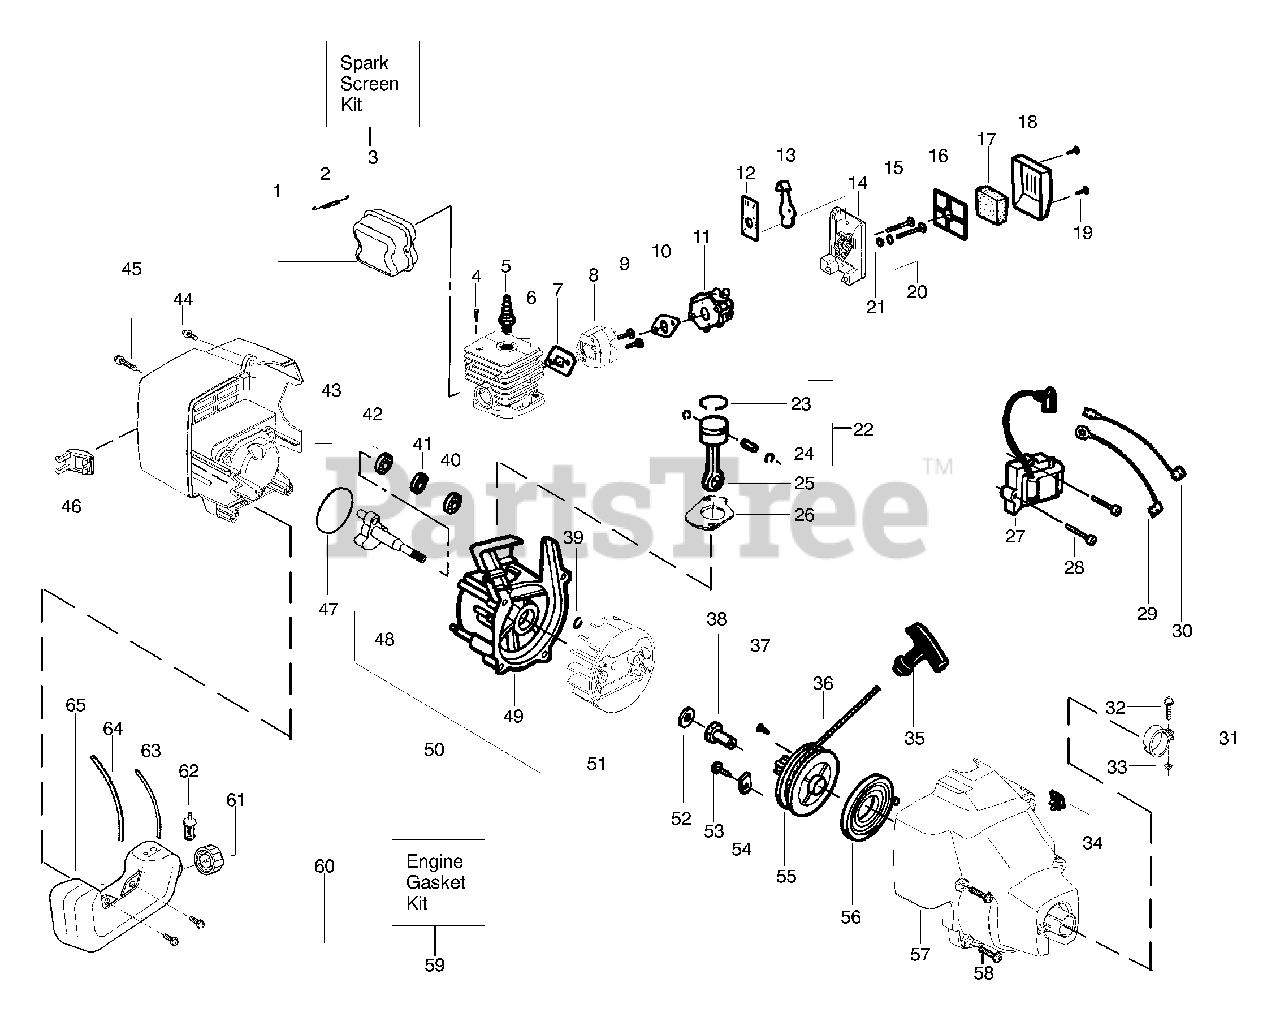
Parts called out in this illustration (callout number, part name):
1	Kit - Muffler
2	Spring-Muffler
3	Kit-Spark Arrestor
4	Screw-Cylinder
5	Spark Plug (RCJ 6Y)
6	Kit - Cylinder
7	Gasket-Cylind./Carb.
8	Adapter-Carb.
10	Gasket-Carb.
11	Kit-Carb.(WT-631)
12	Choke Plate Mounting
13	Shutter-Choke
16	Plate - Filter Support
17	Foam-Air Filter
18	Cover-Air Filter
20	Spacer-Choke
22	Kit - Piston
23	Piston Ring
24	Retainer-Piston Pin
25	Assy-Connecting Rod
26	Gasket-Cylinder
27	Ignition Module
29	Assy-Ground Wire
30	Assy-Leadwire
31	Assy-Nose Cone Clamp
32	Screw-Nose Cone
33	Nut-Nose Cone
34	Kit-On/Off Switch
35	Handle-Starter
36	Kit - Rope
38	Coupling-Drive
39	Retain. Ring-C'shaft
40	Outer Bearing
41	Seal-C'case
42	Inner Bearing
43	Shroud-Rear
45	Screw
46	Guard-Muffler
47	O-Ring-C'case/Shrd
48	Assy-Crankshaft
49	Assy-Crankcase
50	Assy-C'case & C'shaft
51	Assy-Flywheel
52	Washer-Flat
54	Retainer-Can
55	Kit-Starter Pulley
56	Spring-Starter
57	Assy.-Fan Hsg
58	Screw
59	Kit-Engine Gasket
61	Assy-Fuel Cap
62	Assy-Fuel Pickup
63	Kit-Fuel Line (Small)
64	Kit-Fuel Line (Large)
65	Assy-Fuel Tank
